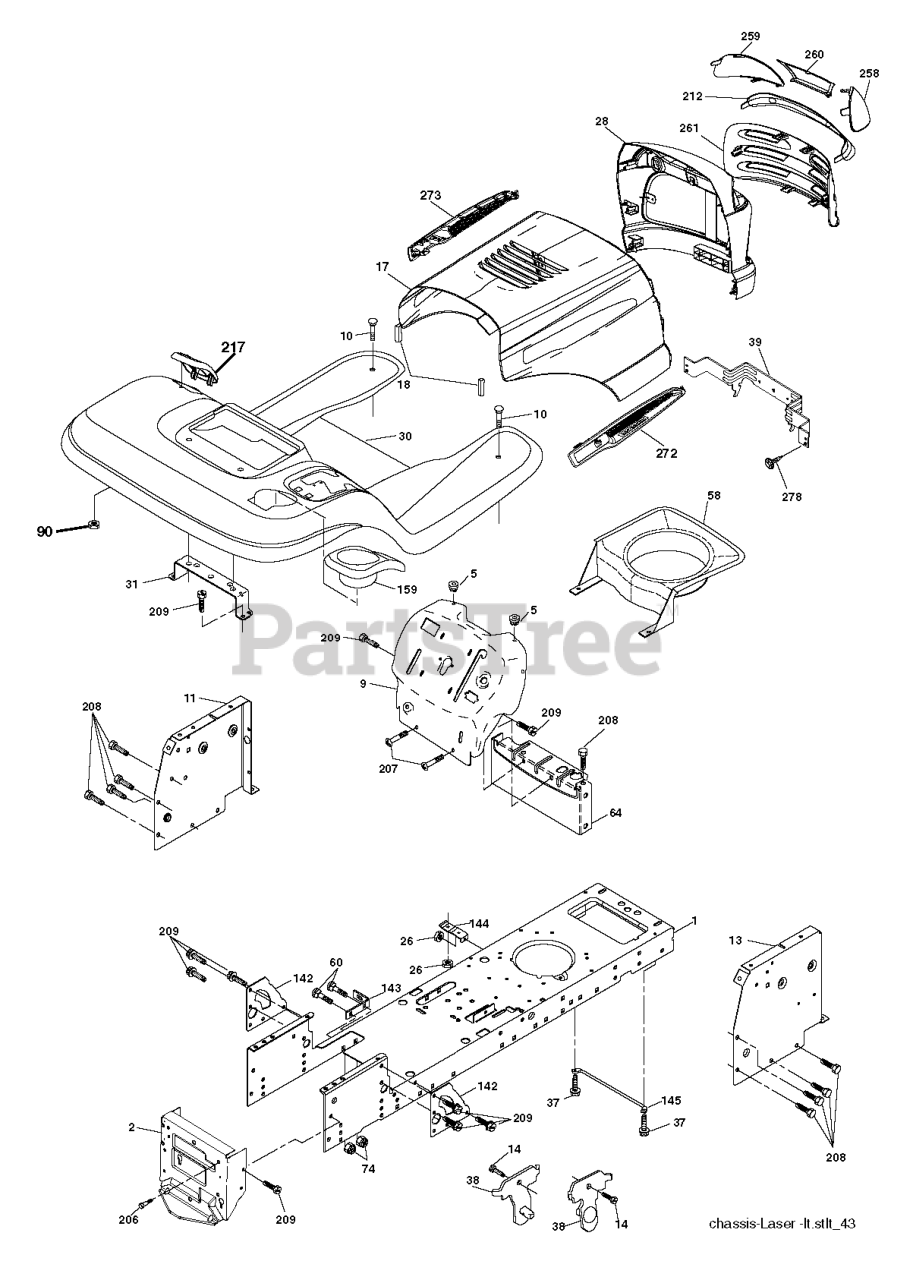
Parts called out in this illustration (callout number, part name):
1	CHASSIS STAMPING
2	DRAWBAR, 12GA
5	BUMPER.RUBBER.HOOD
9	DASH.SLKSCR.STL.PL.E.NA.WHM.CE
10	BOLT D
11	PANEL.DASH.LH.LTX
13	PANEL DASH RH
17	VENT.HOOD.LASER.III
18	BUMPER.HOOD.LARGE.1.75"
26	NUT
30	FENDER
31	BRACKET.SUPPORT.FENDER
37	Screw 5/16-18 x 1/2 Hex, Self Tapping 5/16-18 x 1/2
38	BRACKET.ASM.PIVOT.MOWER.REAR
39	BRACKET PIVOT LASER
60	Bolt - Rd. Hd. Sq. Neckiage 3/8 16 x 3/4
64	DASH LOWER
90	NUT.PUSH.3/16
142	PLATE REINFORCEMENT
143	BRACKET, SWAYBAR CHASSIS
144	BRKT, FOOT REST
145	ROD PIVOT CHASSIS/HOOD
159	CUPHOLDER
206	SHOULDER BOLT 5/16-18TT
207	SCREW, 5/16-18 X 1/2
208	SCREW 3/8-16X1/2
209	SCREW, 3/8-16X3/4
212	INSERT.LENS.REFLECTIVE
217	CONSOLE FUEL WINDOW
258	LENS LH
259	LENS LH
260	COVER.LENS.HUSQ.LASER
272	VENT.HOOD.LASER.
273	VENT.HOOD.LASER.
278	SCREW
